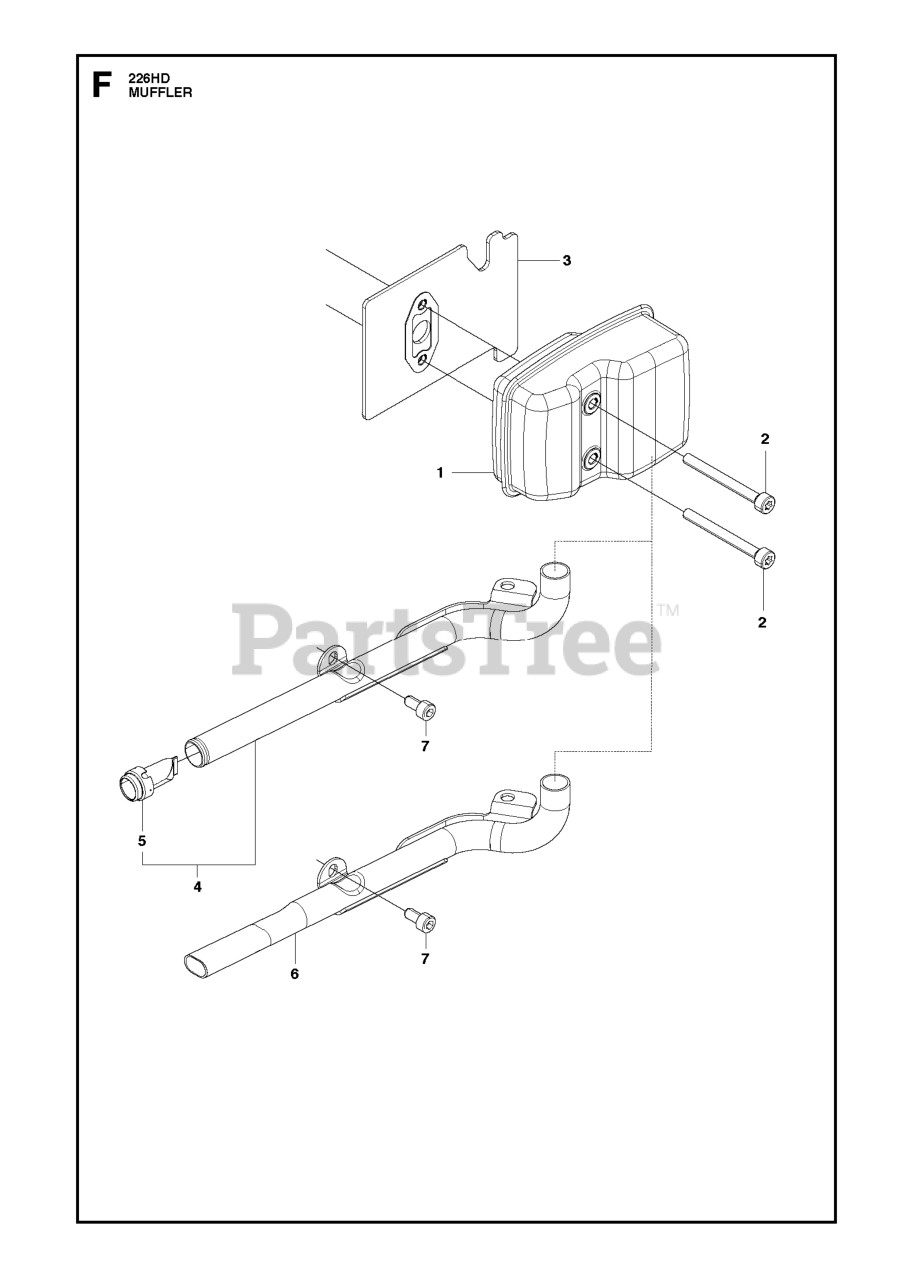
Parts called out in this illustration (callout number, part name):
4	EXHAUST PIPE
6	PIPE-EXHAUST
7	BOLT M5 X L10 ALLEN BOLT
